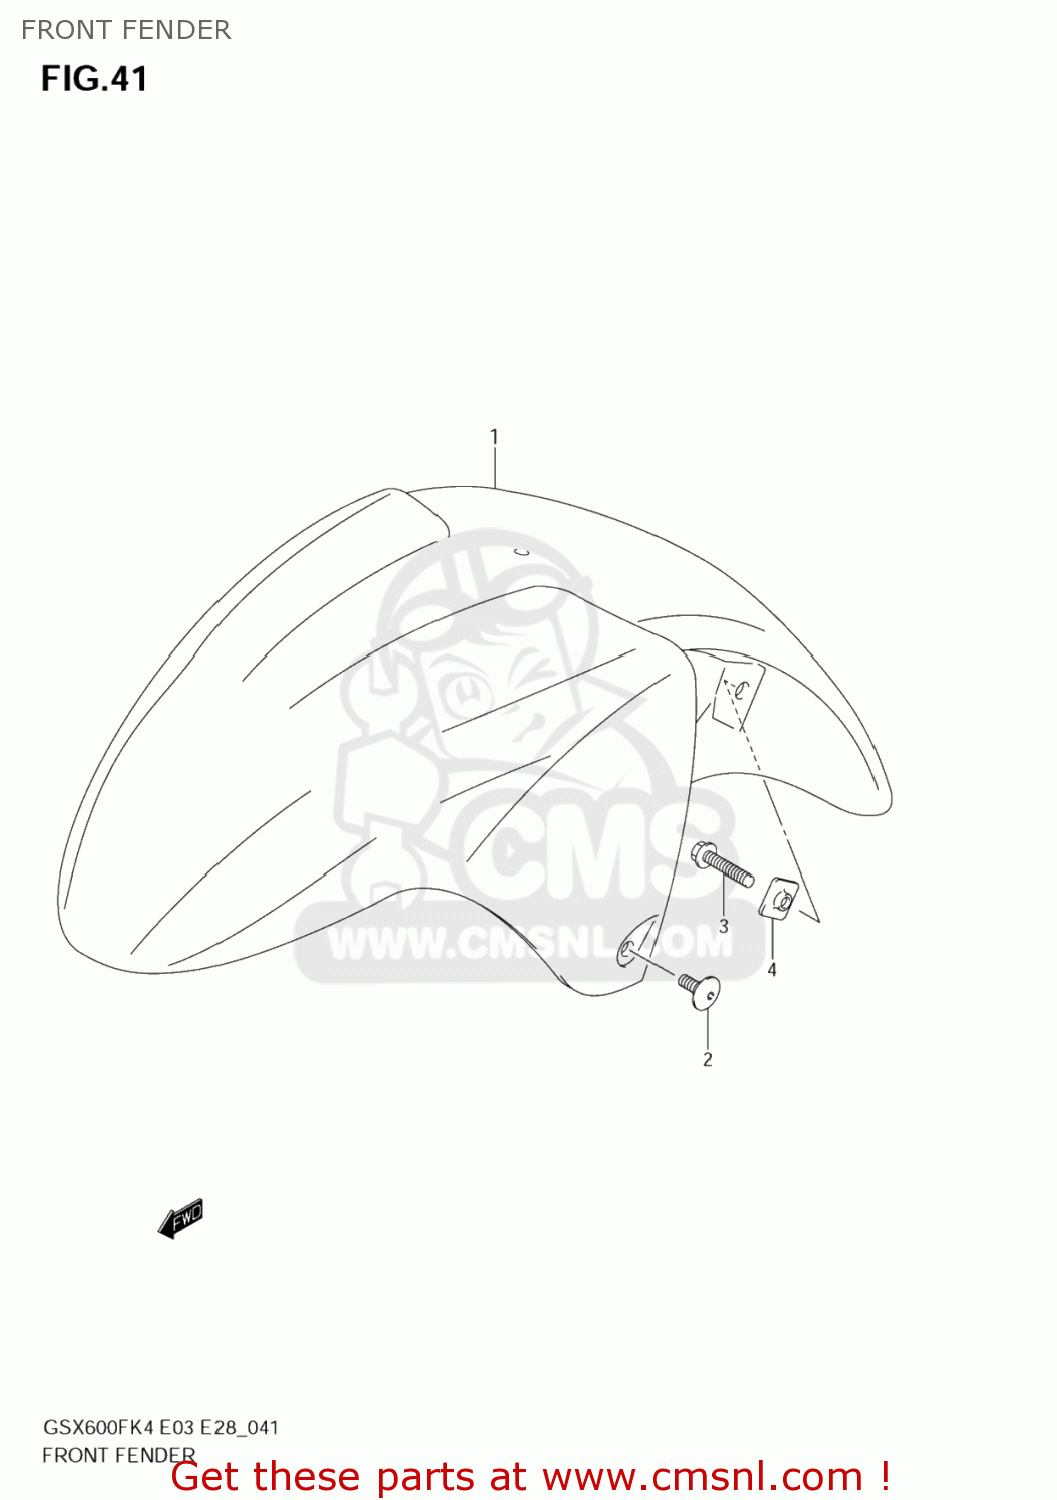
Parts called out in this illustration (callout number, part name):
1	FENDER,FR
2	SCREW(6X16)
3	BOLT
4	NUT,FR FENDER
